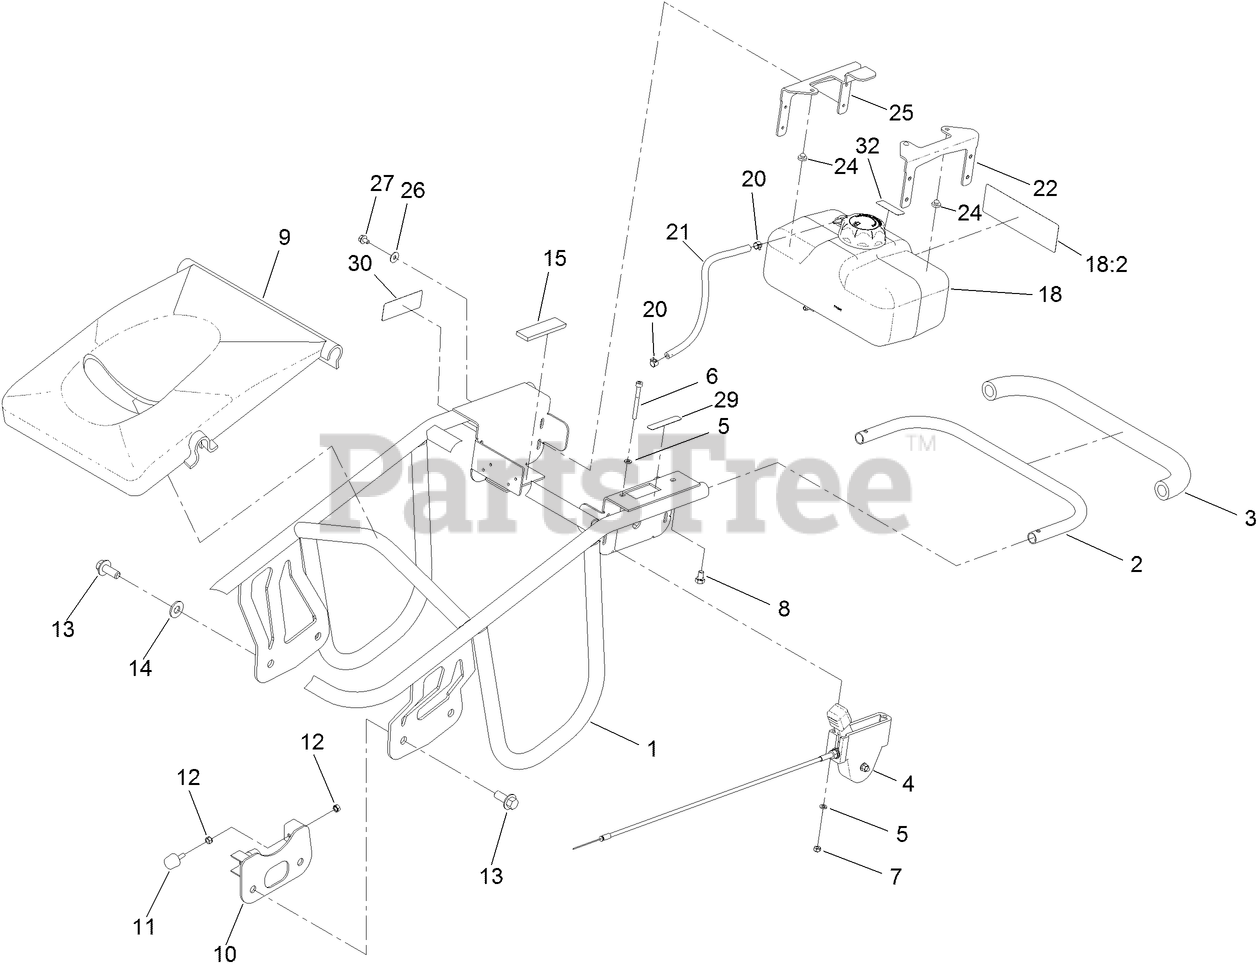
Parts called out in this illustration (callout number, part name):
1	HANDLE ASM
2	HANDLE-GRIP, TUBE
3	GRIP-HAND
4	LEVER-THROTTLE
5	WASHER-FLAT
6	SCREW-HSH
7	NUT-LOCK
9	COVER-ENGINE
10	STOPPER
11	MOUNT-SHOCK
12	NUT-HEX
13	SCREW-HHF
14	WASHER
15	PAD-TANK, FUEL
18	1 GALLON FUEL TANK ASM
18:2	DECAL-WARNING
20	CLAMP-HOSE
21	HOSE-FUEL
22	BRACKET-TOP, FUEL TANK
24	BUMPER-RUBBER
25	GUARD-FUEL TANK, TOP
26	WASHER-FLAT
27	SCREW-HHF
29	DECAL-THROTTLE
30	DECAL-ARRESTER, SPARK
32	DECAL-WARNING, ETHANOL
